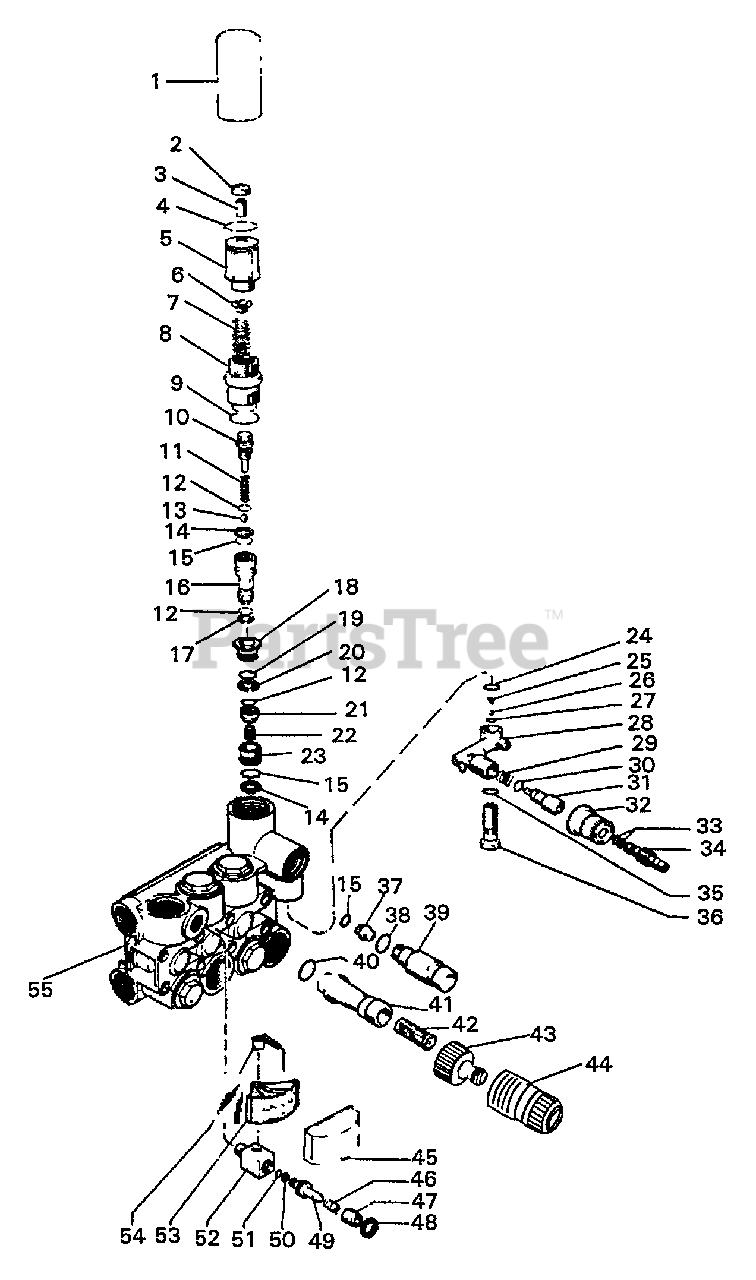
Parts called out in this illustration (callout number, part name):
1	VALVE
2	NUT - 8
3	SCREW M8×16
4	O-RING 20 35×1 78
5	SCREW, PRESSURE SET
6	PLATE, SPRING
7	SPRING
8	BUSHING, GUIDE
9	O-RING 0.797×.103
10	STOPPER, STROKE
11	SPRING
12	O-RING
13	BALL - 9/32"
14	RING, ANTI-EXTRUSION
15	O-RING 9 92×2 62
16	PISTON, CONTROL
17	RING, ANTI-EXTRUSION
18	GUIDE, VALVE
19	O-RING
20	RING, ANTI-EXTRUSION
21	VALVE, BALL
22	SCREW M5×8×75
23	SEAT, VALVE
24	O-RING
25	SPRING, TAPER
26	BALL
27	O-RING 5 28×1 78 VITON
28	INJECTOR BODY
29	SPRING
30	O-RING
31	SHUTTER, INJECTOR
32	KNOB, CHEMICAL REGULATOR
33	O-RING
34	FITTING, HOSE BARB
35	O-RING
36	SEAT, CHEMICAL VALVE
37	NOZZLE, INJECTOR
38	O-RING
39	FITTING, GREASE
41	FITTING, GREASE
43	COUPLING, QUICK CONNECT - MALE
44	COUPLING, QUICK CONNECT - FEMALE
45	COVER
46	SPRING
47	SCREW M14×1
48	NUT M14×1×17×3
49	PISTON
50	RING
51	O-RING 3 63×1 78 VITON
52	BODY
53	DIAL
54	INDICATOR
55	MANIFOLD
